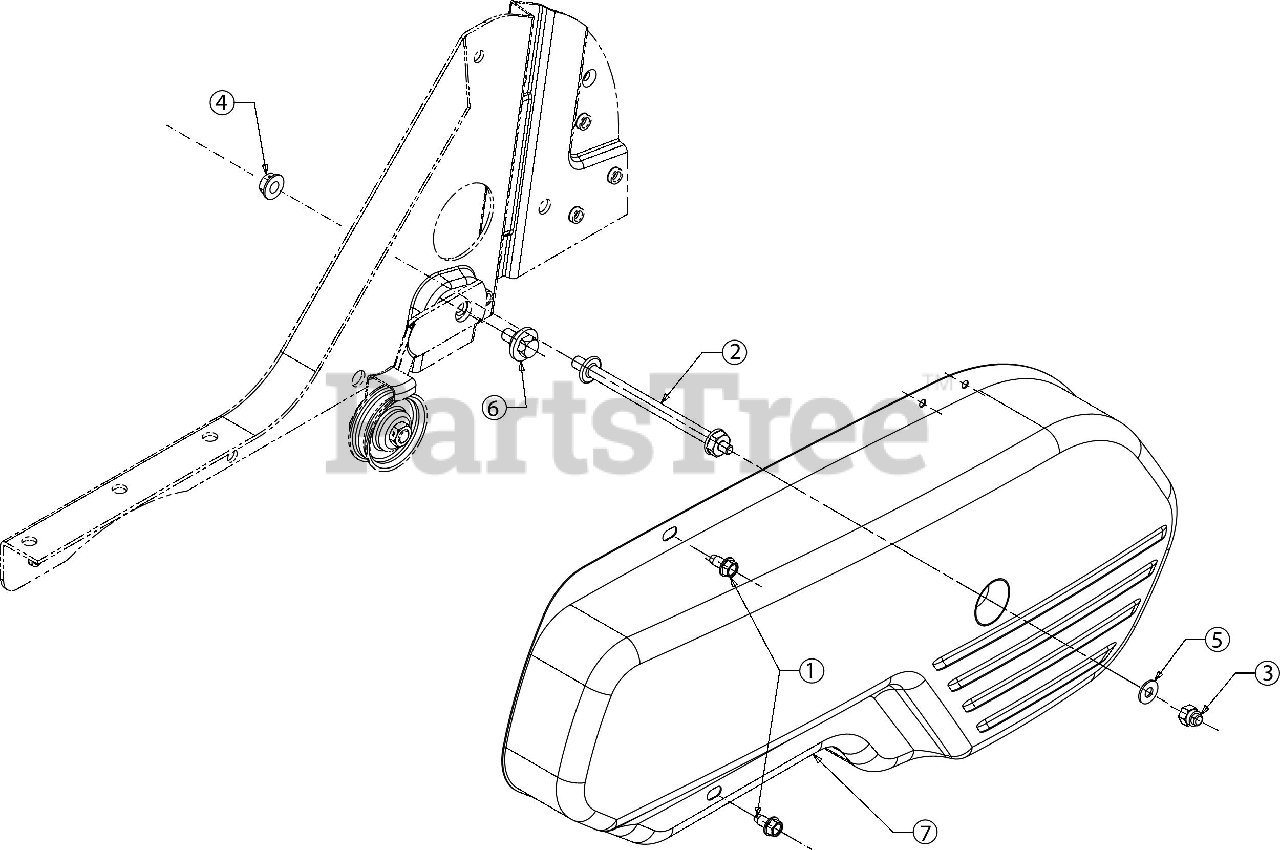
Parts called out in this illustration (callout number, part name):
1	SCREW 1/4-20 X.500
2	BELT COVER BOLT
3	HEX ACORN NUT
4	HEX FLANGE NUT
5	FLAT WASHER .271:.630:.065
6	SHOULDER SCREW .560X.165: 5/16-18
